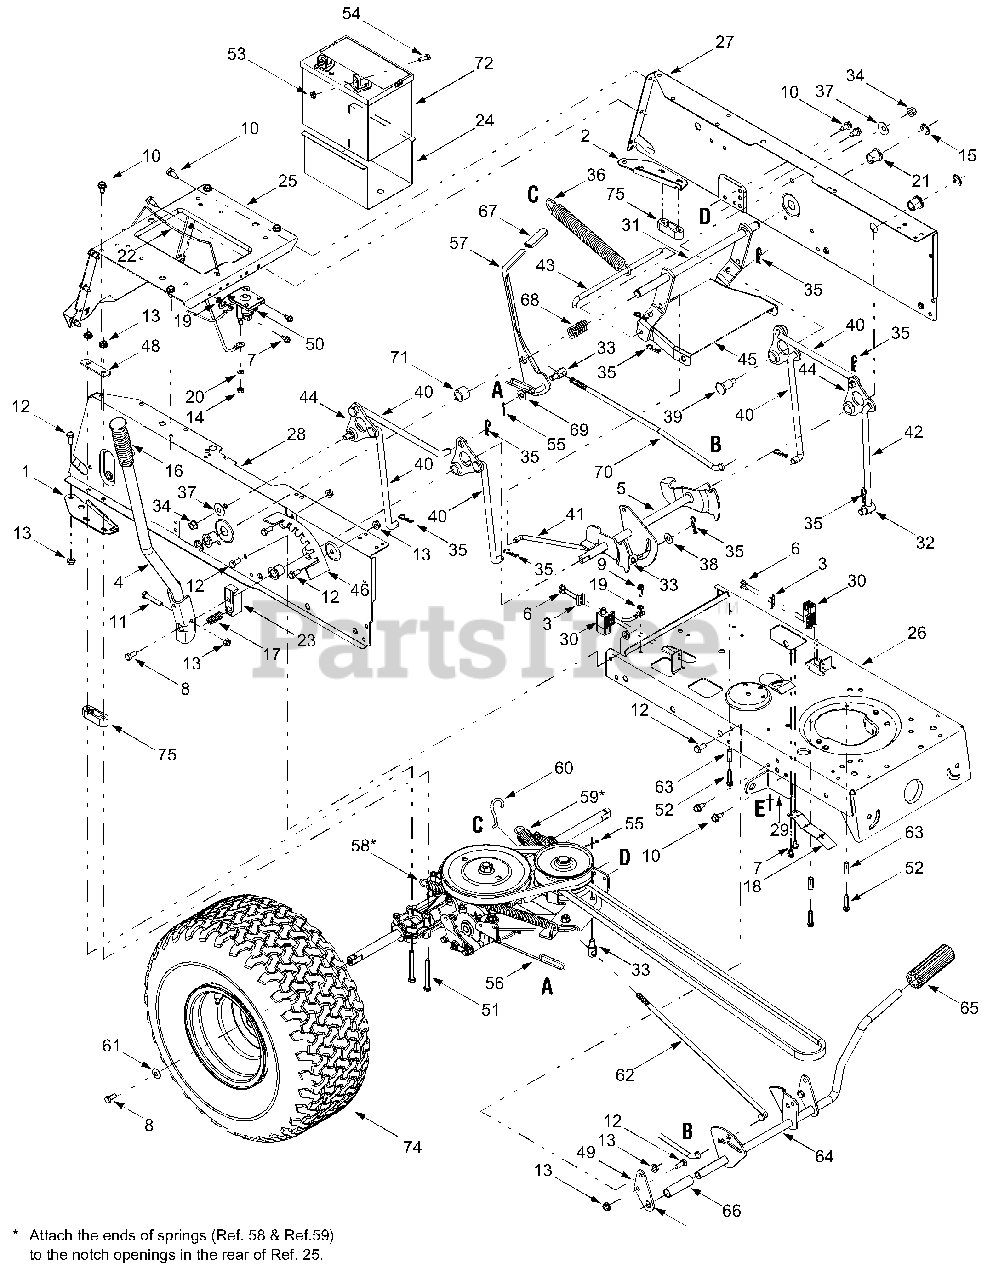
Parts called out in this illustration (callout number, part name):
6	Self-tapping Screw, #10-16 x .5
7	Self-tapping Screw, 1/4-20 x .5
8	Hex Cap Screw, 5/16-24 x .75
9	Self-tapping Screw, 1/4-20 x .75
10	Self-tapping Screw, 5/16-12 x .75
11	Hex Cap Screw, 5/16-18 x 1.75
12	Hex Screw, 5/16-18 x .75
13	Hex Lock Nut, 5/16-18
14	Hex Nut, 1/4-20
15	E-Ring, .625 Dia Shaft
16	Handle Grip
17	Compression Spring, .55 x 1.37
18	Switch Actuator Spring
19	External Lock Washer, 1/4
20	Lock Washer, 1/4
21	Flange Bearing, .632 ID
22	Battery Hold-down Rod
23	Lift Shaft Connector
33	Ferrule, 3/8-24 x .375
34	Hex Lock Nut, 3/8-16
35	Internal Cotter Pin, .080 x 1.56
36	Extension Spring, 1.07 x 9.52
37	Bell Washer, .389 x 1.12 x .030
38	Flat Washer, .385 x .87 x .060
39	Shoulder Bolt, .625 x .217
40	Deck Hanger Link
41	Deck Disengagement Rod
42	Deck Hanger Link
43	Rear Stabilizer Rod
44	Lift Link
46	Deck Lift Index Bracket
51	Hex Cap Screw, 5/16-18 x 2.75
52	Self-tapping Screw, 1/4-20 x 1.25
53	Hex Sems Nut, 1/4-20
54	Hex Screw,1/4-20 x .75
55	Cotter Pin
56	Extension Spring, .59 x 12.38
57	Speed Select Lever
58	Extension Spring, .73 x 12.54
59	Extension Spring, 1.15 x 7.90
60	Brake Return Spring
61	Bell Washer, .34 x .872 x .060
62	Variable Speed Control Rod
63	Spacer, .260 x .372 x 1.030
66	Spacer, .640 x .76 x 2.63
67	Shift Handle Grip
68	Compression Spring, .89 x 1.75
69	Flat Washer, .406 x .875 x .059
70	Speed Control Rod
71	Spacer, .640 x 1.0 x .78
72	Battery, 190 CCA
73	Flange Lock Nut, 1/4-20
75	Spacer
